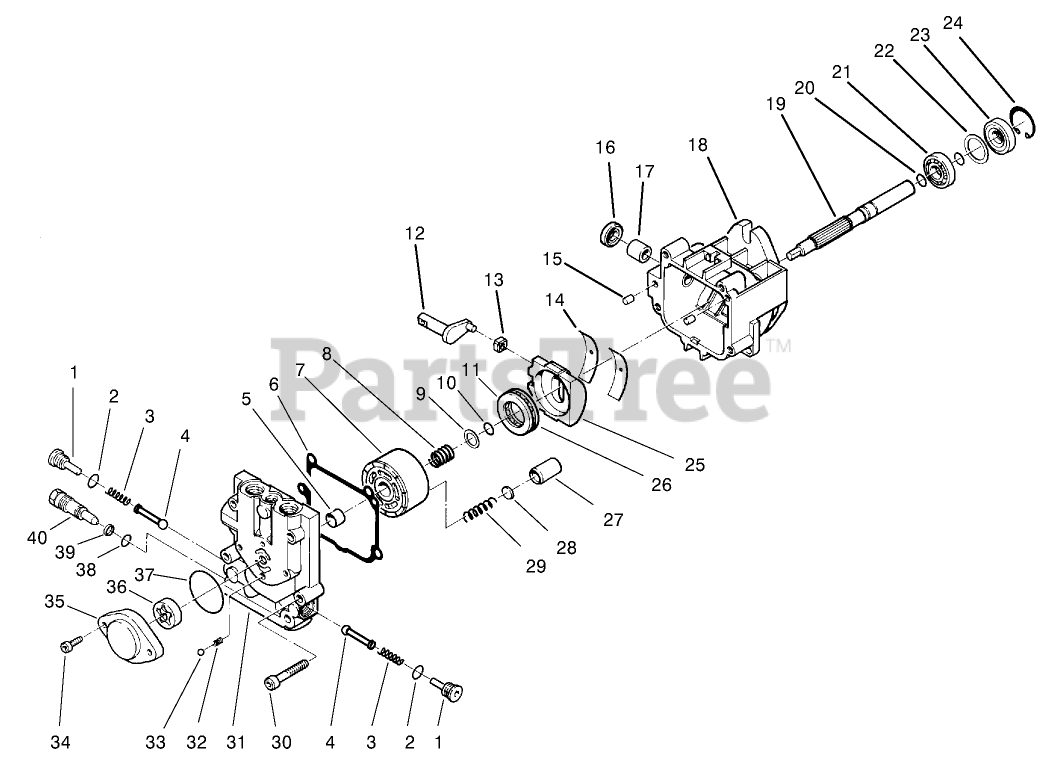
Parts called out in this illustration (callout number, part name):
2	Seal-O-Ring
3	Spring
4	Poppet
5	Journal-Bearing
6	Gasket-End Cap
8	Spring
9	Washer
10	Ring-Retaining
11	Plate-Thrust
12	Arm-Trunnion
13	Guide-Slot
14	Cradle-Bearing
15	Pin
16	Seal-Lip
17	Journal-Bearing
19	Shaft
20	Ring-Retaining
21	Bearing-Ball
22	Spacer
23	Seal-Lip
24	Ring-Retaining
25	Swashplate Assembly
26	Roller-Thrust
27	Piston
28	Washer-Thrust
29	Spring-Piston
30	Screw
32	Ball
33	Spring
34	Screw
35	Housing-Charge Pump
36	Gerotor Assembly
37	Seal-O-Ring
38	Seal-O-Ring
39	Ring-Back-Up
40	Valve-Bypass
